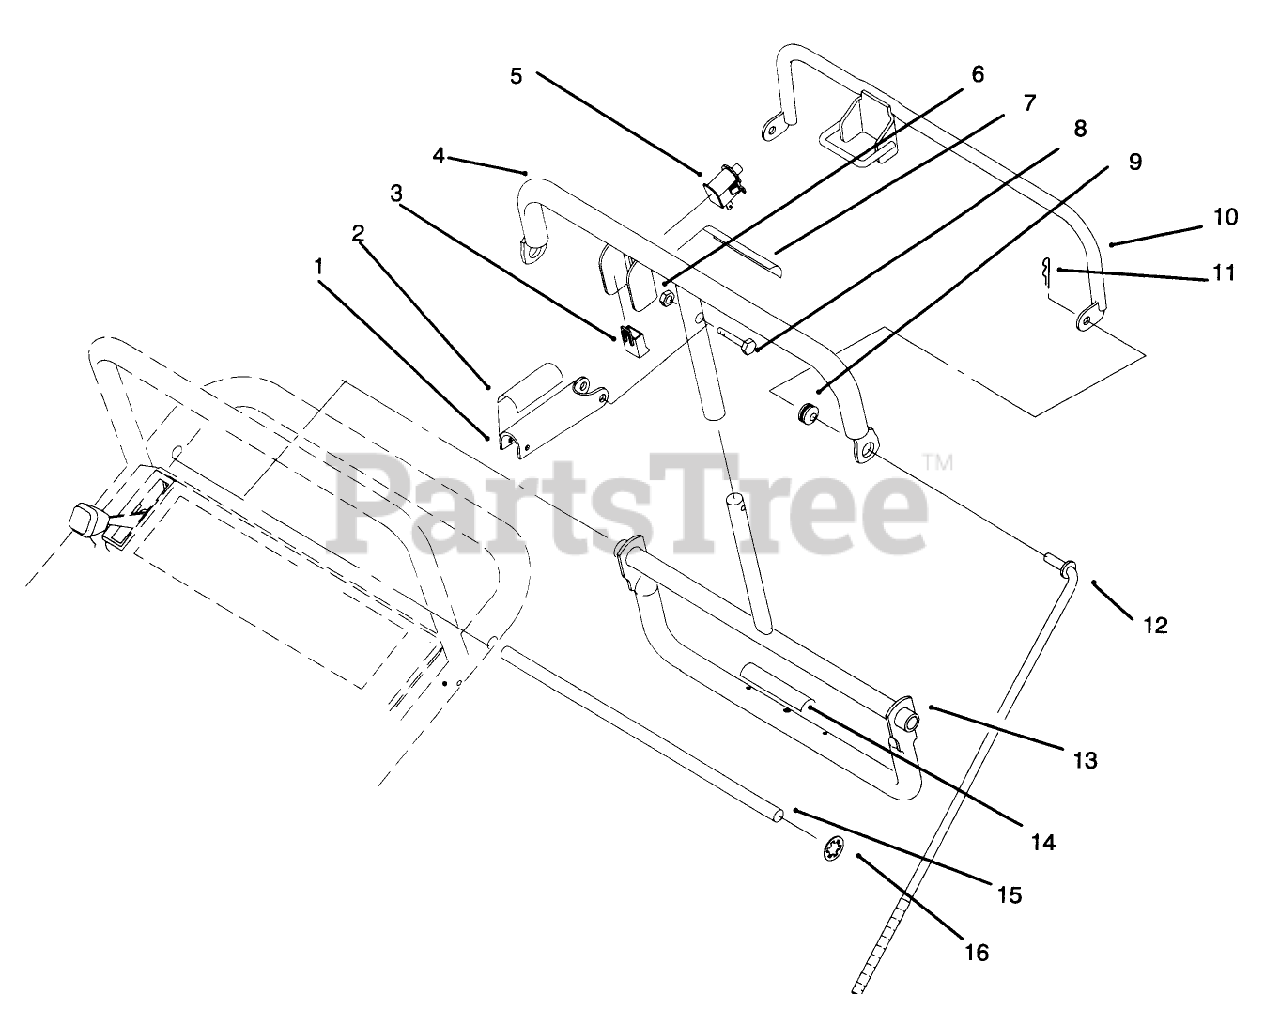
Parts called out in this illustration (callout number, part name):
1	Lever-Parking Brake
2	DECAL-LEVER, PARKING
3	CONNECTOR-BODY
4	Bar
5	SWITCH-BAIL
6	NUT-LOCK, NI
7	DECAL
8	SCREW-SHH
9	GROMMET-RUBBER
10	Bail
11	PIN-COTTER
12	ROD-CONTROL
13	Control Pivot
14	DECAL
15	PIVOT ROD
16	NUT-PUSH-ON, CIRCULAR
